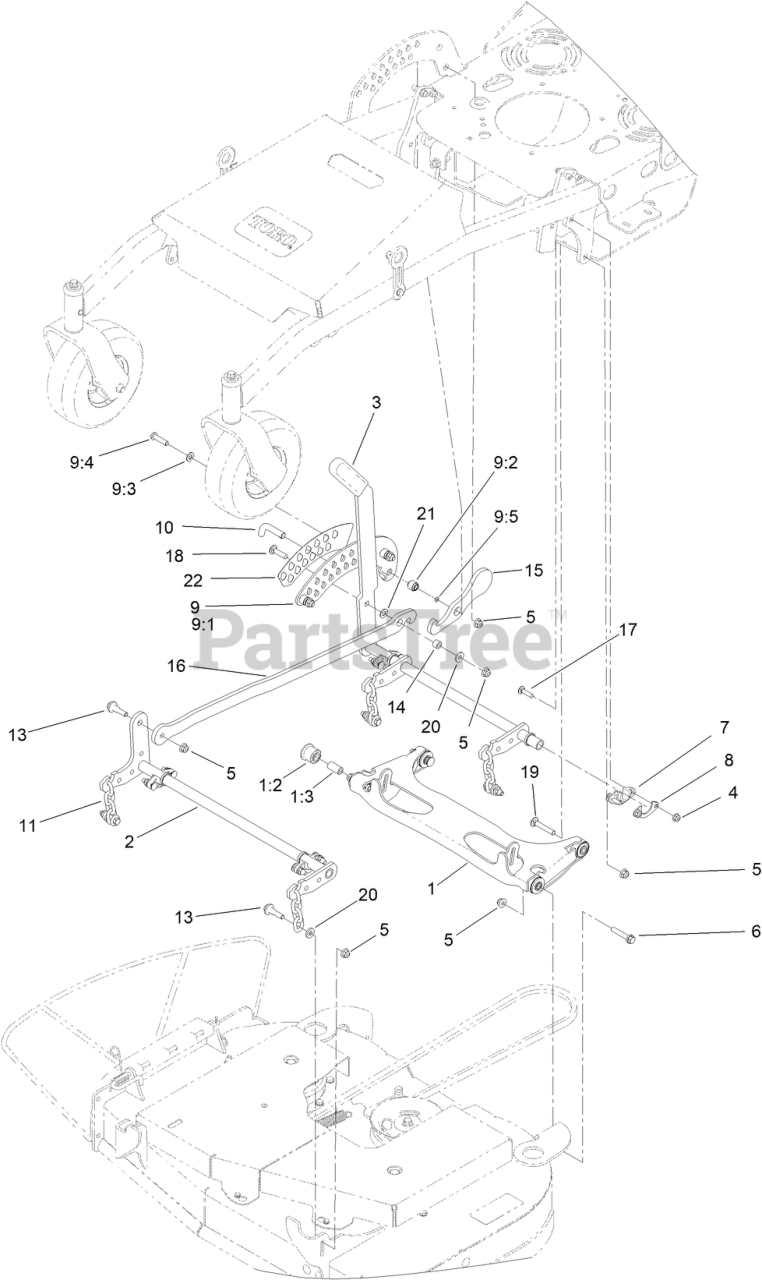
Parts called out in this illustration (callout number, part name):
1	DECK STRUT ASM
1:2	BUSHING-RUBBER, SUSPENSION
1:3	SPACER
2	PIVOT ASM-FRONT
3	PIVOT ASM
4	NUT-HF, NI
5	NUT-HF, NI
6	SCREW-HHF
7	BEARING-FLANGE
8	GUSSET-DECK LIFT
9	HOC STANDOFF ASM
9:1	PLATE - HOC
9:2	SPACER-DOUBLE STEP
9:3	WASHER-PLAIN
9:4	SCREW-HSBH
9:5	O-RING
10	PIN-HOC
11	CHAIN-DECKLIFT, 4-LINK
13	BOLT-SHOULDER
14	SPACER
15	LEVER-LOCK
16	LINK-HOC
17	SCREW-CARR
18	SCREW-CARR
19	SCREW-CARR
20	SPACER-HUB, BLOWER
21	WASHER-PLAIN
22	DECAL-HOC
